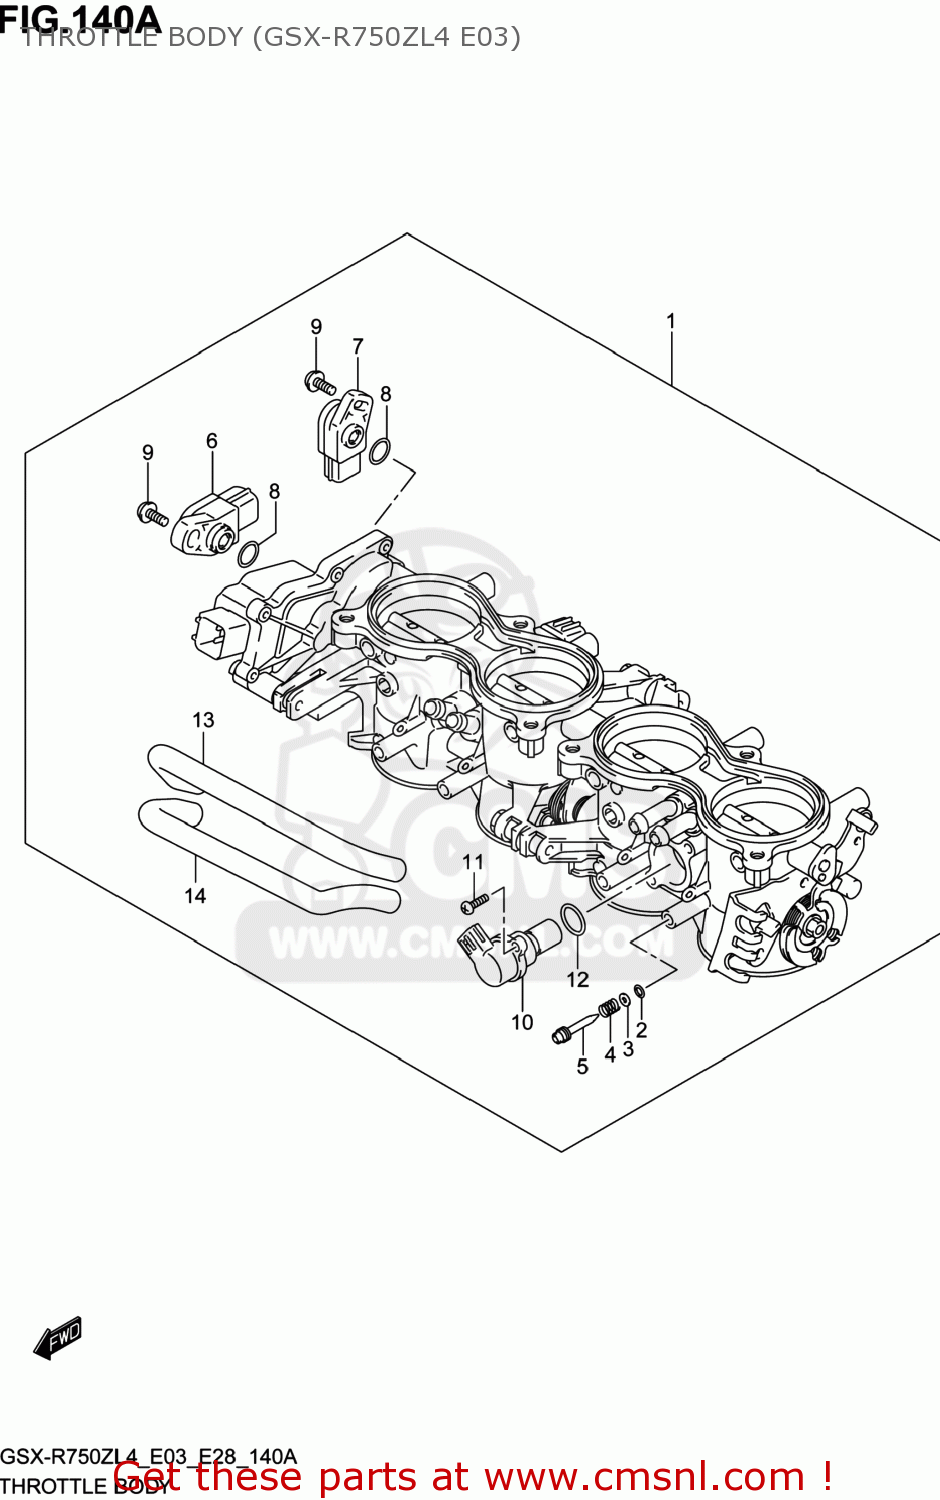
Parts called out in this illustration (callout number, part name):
1	BODY ASSY,THROTTLE
2	O RING,PILOT AIR SCREW
3	WASHER
4	SPRING,THROTTLE SCREW
5	SCREW
6	SENSOR
7	SENSOR
8	O RING
9	SCREW
10	MOTOR ASSY
11	SCREW
12	O RING
13	HOSE
14	HOSE
